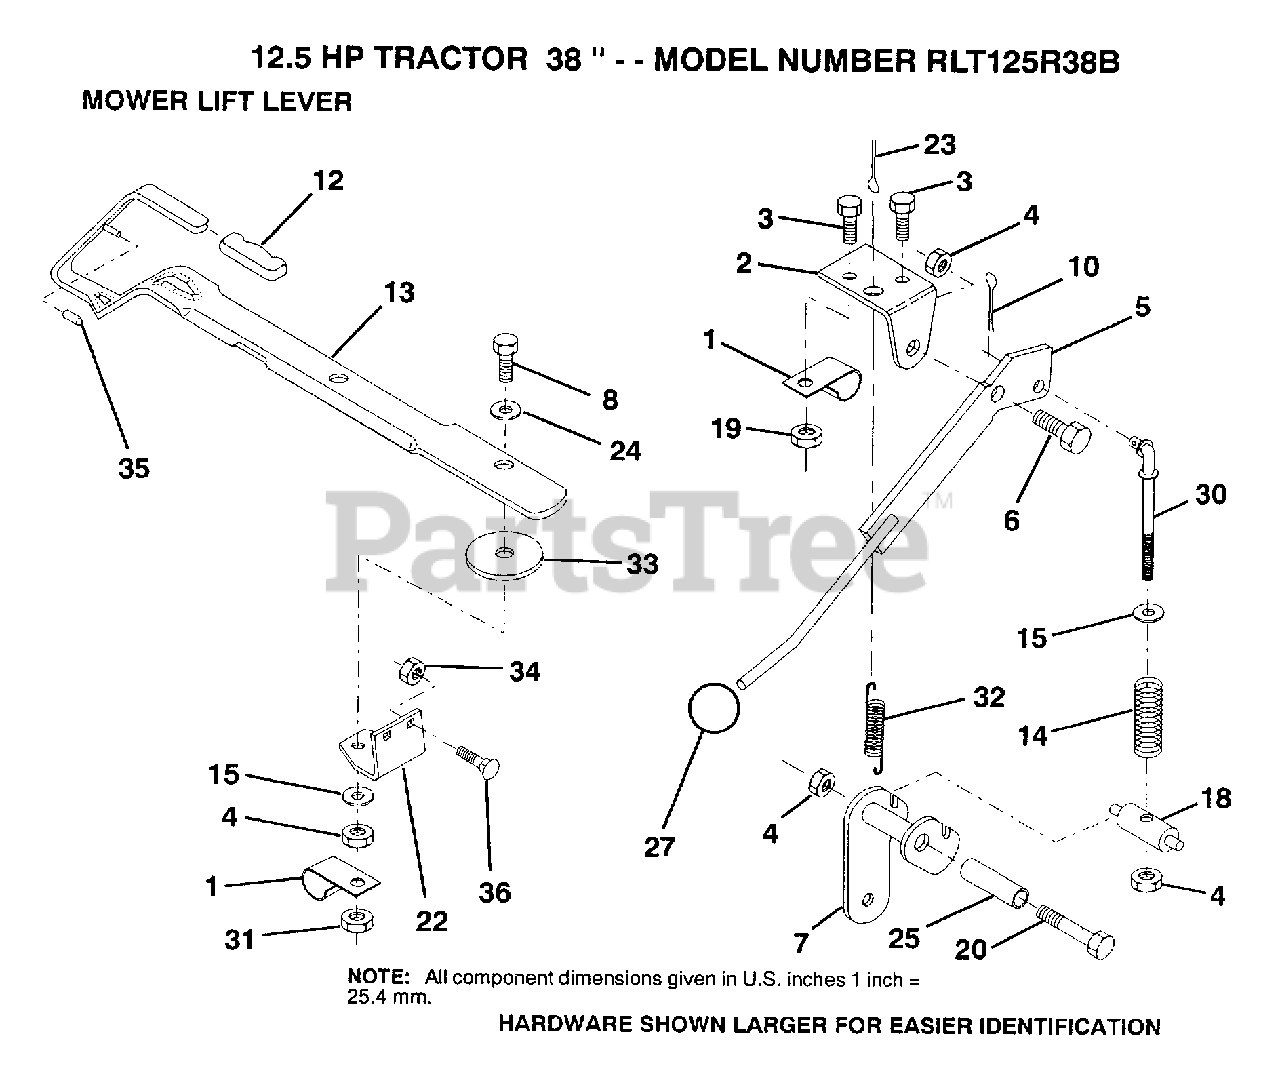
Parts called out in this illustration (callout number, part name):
1	"CLIP,INSULATOR"
2	BRKT CLUTCH
3	BOLT
5	CLUTCH LEVER AS
6	"BOLT, SHOULDER LT"
7	MWR CLUT ARM ASM
8	BOLT
10	COTTER PIN
12	GRIP HANDLE
13	LEVER LIFT LR
14	COMP CLUTCH SPRNG
15	WASHER HYT
18	TRUNNION
20	BOLT
22	LIFT LEVER BRKT
24	WASHER
25	TUBE SPACER
27	KNOB
30	ROD TENSION CLUTC
31	LOCKNUT
32	SPRING EXT
33	WASHER
35	VINYL CAP RED
36	BOLT
